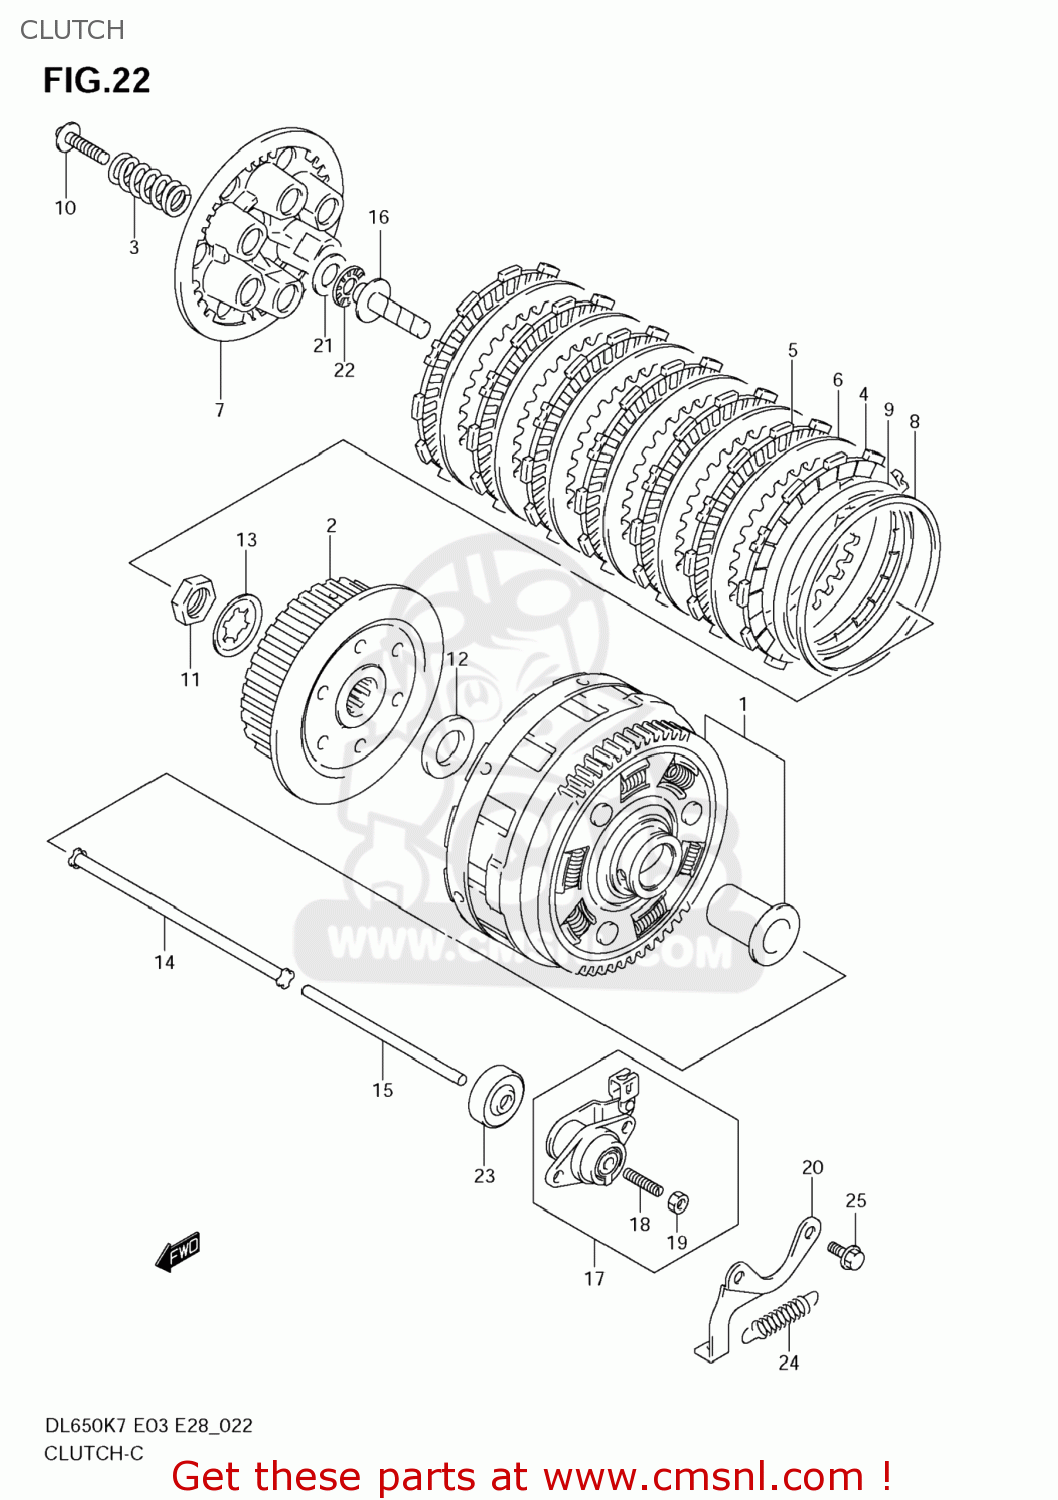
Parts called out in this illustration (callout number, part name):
1	GEAR ASSY,PRI DRIVEN
2	HUB,CLUTCH SLEEVE
3	SPRING,CLUTCH
4	PLATE,CLUTCH DRIVE NO.2 (NAS)
5	PLATE,CLUTCH DRIVE (NAS)
6	PLATE,CLUTCH DRIVEN(T:1.6) (NAS)
7	DISC,CLUTCH PRESSURE
8	SEAT,WAVE WASHER
9	WASHER,CLUTCH PLATE WAVE
10	BOLT(6X30)
11	NUT
12	WASHER(20X36X3)
13	WASHER,LOCK
14	ROD,PUSH,R
15	ROD,CLUTCH PUSH,L
16	PIECE,CLUTCH PUSH
17	SCREW ASSY,CLUTCH RELEASE
18	SCREW(6X25)
19	NUT
20	SUPPORT,CL RLSE RETURN SPRING
21	WASHER(15.5X28X1)
22	BEARING(15X28X2)
23	SEAL,OIL(6X34X5.5)
24	SPRING
25	BOLT
